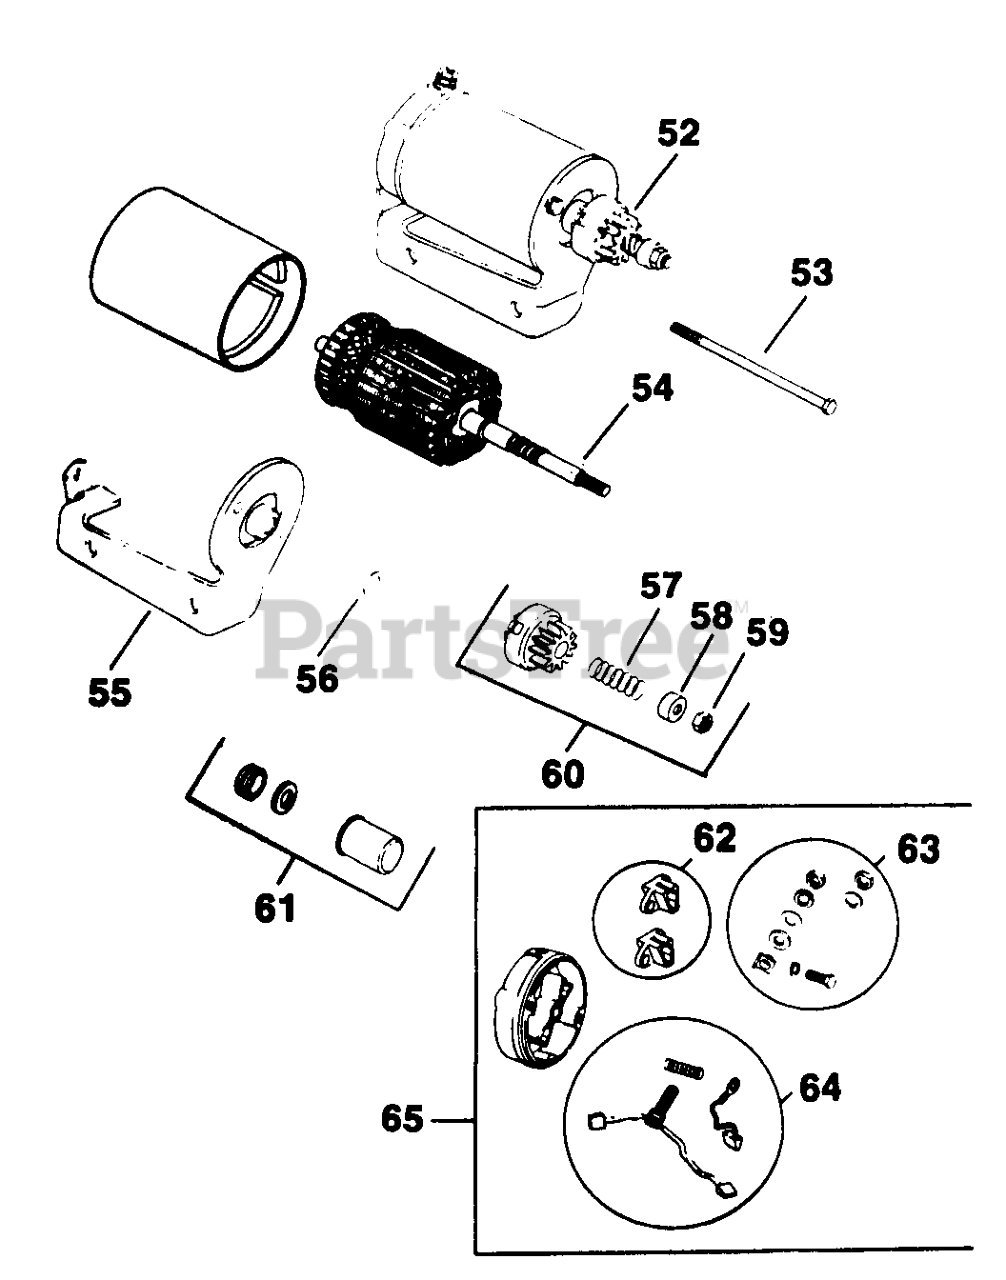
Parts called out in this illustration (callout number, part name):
52	STARTER - USE A-237534
53	BOLT - USE 237758
54	ARMATURE - USE 47 170 01
56	WASHER - USE 47 468 02
57	SPRING - USE 45 089 03
58	KIT - USE 47 755 13
60	KIT DRIVE - USE 47 755 07
64	KIT - USE 277613
65	ARMATURE - USE 47 170 01
